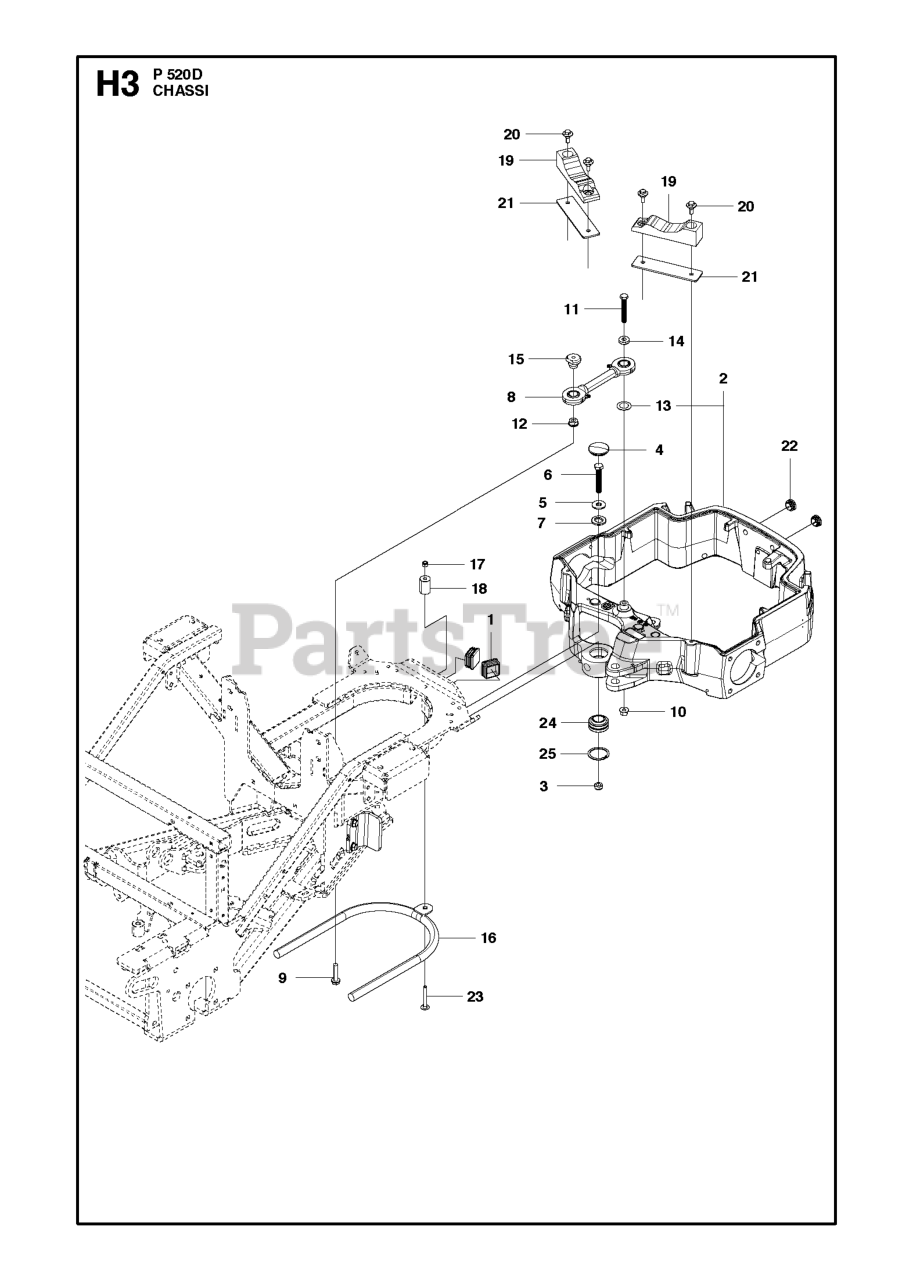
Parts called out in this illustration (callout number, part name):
4	HUB CAP PIVOT WHEEL
17	LOCKNUT M8
20	COLLAR SCREW
